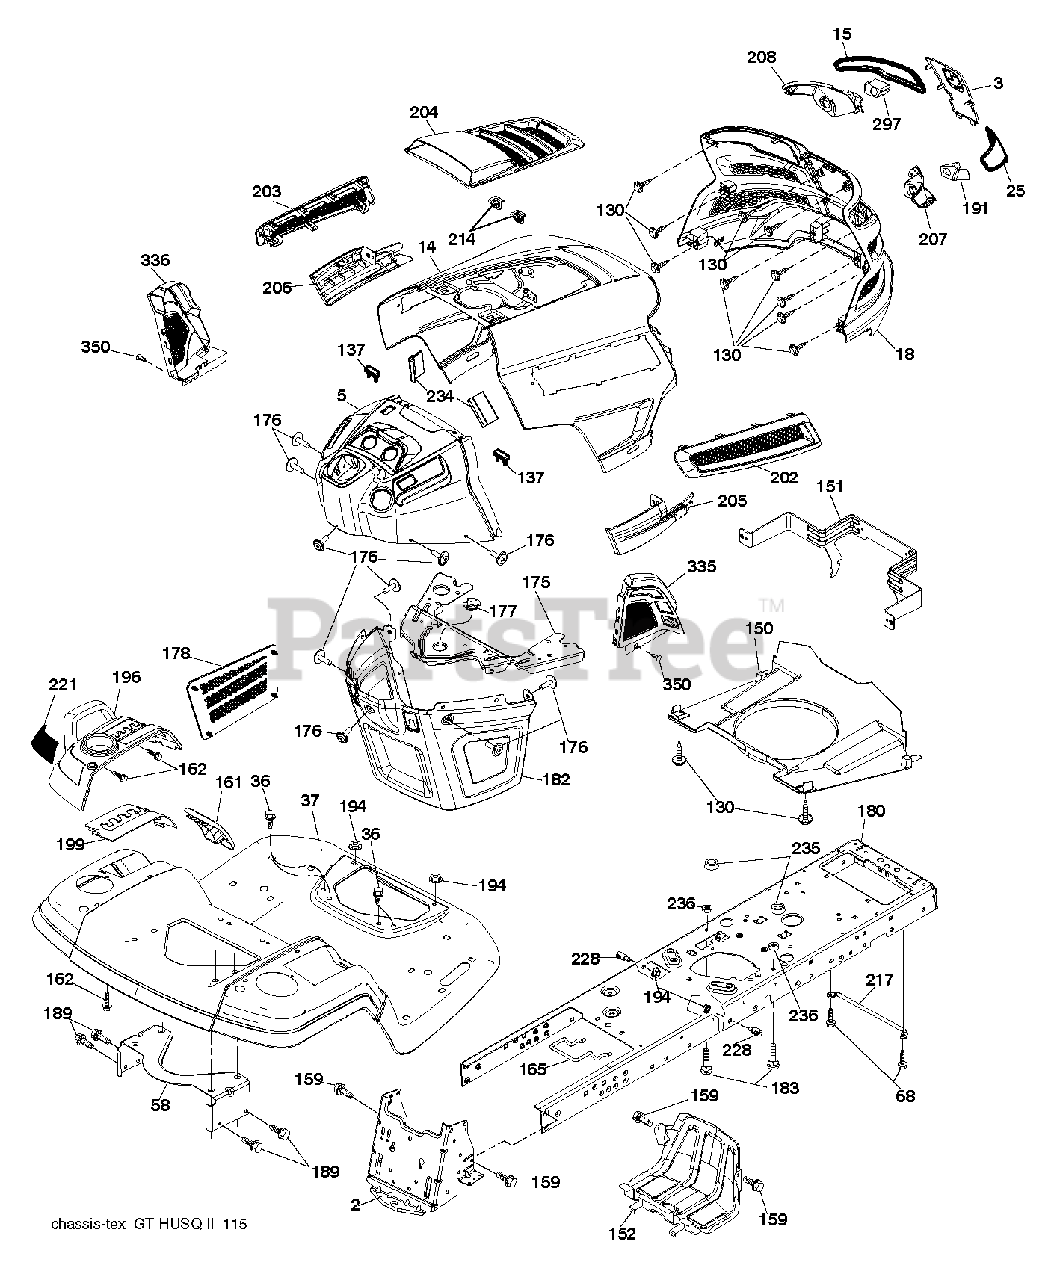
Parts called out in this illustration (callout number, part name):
2	DRAWBAR.STGT
3	APPLIQUE.SUBASM.GT.HUSQ.II
5	DASH.UPP.GT2.DUAL.RD.PTO.MCHOK
14	HOOD.ASM.HUSQVARNA.GT.TEX.ORAN
15	LENS.HEADLIGHT.LH.GTII.2011
18	GRILLE.SUBSTRATE.2011.
25	LENS.HEADLIGHT.RH.GTII.2011
36	SCREW 5/16"
37	FENDER.PNT.TX.GT.CH/FW/DL.HUSQ
58	BRKT.SUPPORT.FNDR/TANK
68	SCREW LT
130	SCREW.#10 X 0.750.BOS
137	BUMPER DASH
150	AIR.DUCT.GTV.BLACK
151	BRACKET.PIVOT.HOOD.GT.HUSQ.II
152	SHIELD.BROWNING.PNT.GT.V2
159	SCREW, 3/8-16X3/4
161	CONSOLE.WINDOW.FUEL.HUSQ.GT
162	SCREW.HI-LO.CONSOLE
165	SUPPORT.TANK.REAR.B/TE
175	PLATE.CROSSMEMBER.HUSQ
176	SCREW.#10-24X5/8.RN.QU
177	BUSHING, STEERING
178	CARGO.ASM.NET.TXGT.W/C
180	CHASSIS.TEX.BOLTED
182	DASH.LOWER.COMMON.12V.ADAPTOR
183	BOLT.5/16-18X1-1/4 FULL THD
189	SCREW
191	INSERT.REFLECTIVE.RH.HUSQ.GTII
194	NUT LOCK HEX FLANGE 5/16-18
196	CONSOLE.ASM.DECKLIFT.HUSQGT.DL
199	PLATE.DECK.LIFT.HUSQVARNA.GT
202	VENT.SIDE.RH.GT.HUSQ.II.
203	VENT.SIDE.LH.GT.HUSQ.II.498
204	VENT.TOP.HUSQ.GT2
205	SIDE.TRIM.RH.GT.HUSQ.II
206	SIDE.TRIM.LH.GT.HUSQ.II.GRAY
207	BEZEL LIGHT.RH.GT.II.MYLAR
208	BEZEL LIGHT.LH.GT.II.MYLAR
214	CLIP.RETAINER.TINNER.
217	ROD.PIVOT.HOOD
221	REFLECTOR.LH.TEX GT HU
228	STUD.FASTNER.W/ANTI-ROTATE
234	BUMPER.HOOD.TEX.HUSQVARNA
235	SPACER FENDER
236	NUT.CENTERLOCK.5/16-
297	INSERT.REFLECTIVE.LH.HUSQ.GTII
335	COVER.LOWER.DASH.RH.BLACK
336	COVER-LH.LOWER.DASH.GT2.BLACK
350	CLIP.X-MAS.TREE
